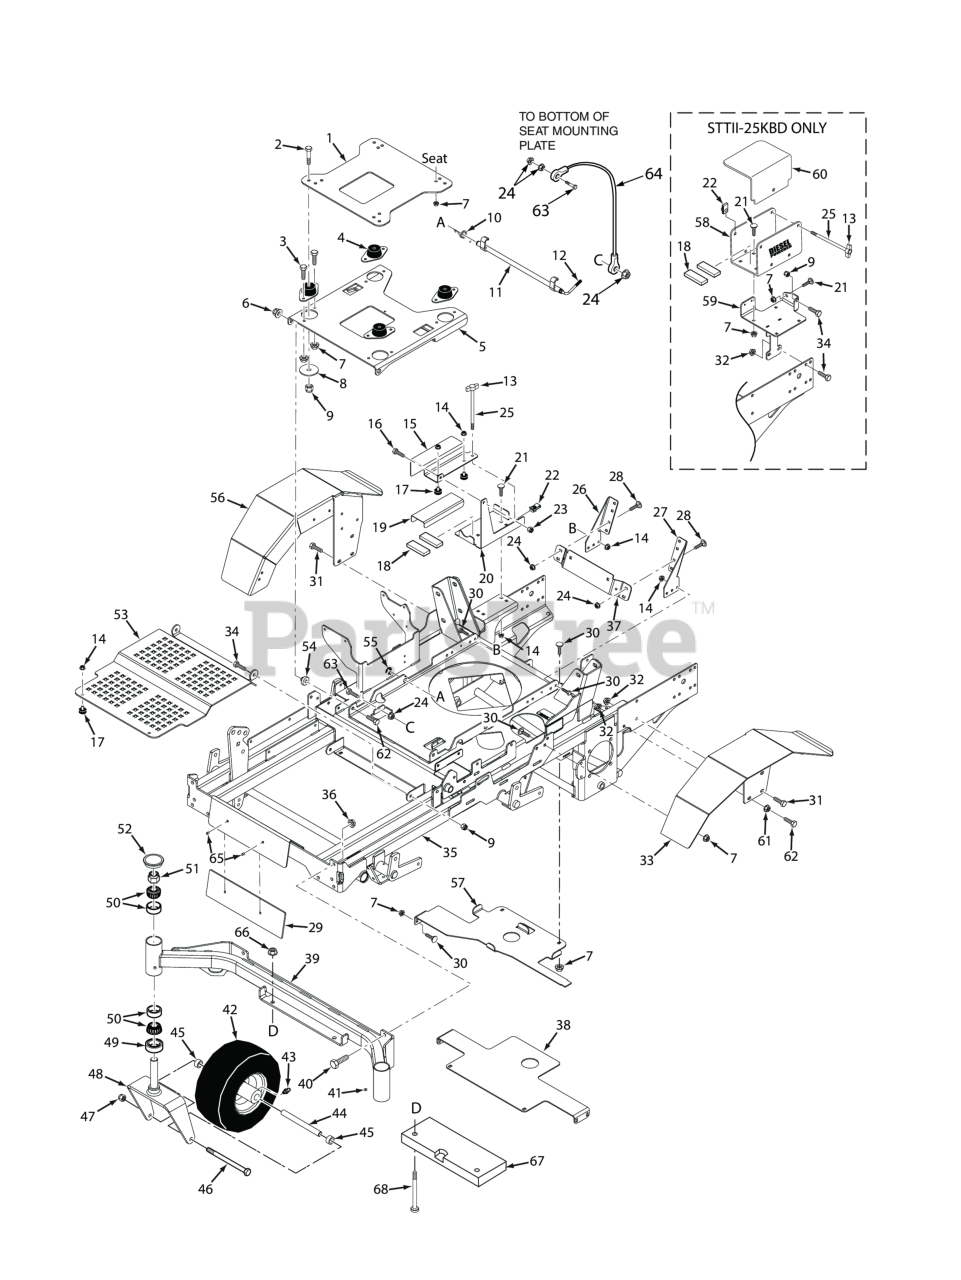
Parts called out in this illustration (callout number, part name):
1	Mounting Plate, Seat w/Decal
2	Bolt, Hex Head 3/8-16 x 2-1/4" - 61"
3	BOLT, SERRATED FLANGE HEX HEAD 5/16-18 X 3/4"
4	Isolator, Seat
5	Seat Mounting Plate, Lower w/Decals
6	Nut, Flange Elastic Stop Nut, 3/8-16
7	Nut, Serrated Flange 5/16-18 (Right Front Engine Mounting, Briggs and Kohler Only)
8	Flatwasher, 3/8-.406 x 2.25" x .1875
9	HEX NUT, ELASTIC STOP LOCK, 3/8-16
10	Spring, Seat Latch
11	Lever Assy., Seat Release
12	Grip, Seat Latch
13	Knob, 1/4" Wing
14	Nut, Serrated Flange 5/16-18 (Right Front Engine Mounting, Briggs and Kohler Only)
15	Cover, Battery Box w/ Decal (Gas & LP)
16	BOLT, SERRATED FLANGE HEX HEAD 5/16-18 X 3/4"
17	Bumper, Rubber 5/16-18 x 5/8"
18	PAD, BATTERY SUPPORT
19	Insulation, Battery Cover (Gas Only)
20	Battery Box (Gas Only)
21	Bolt, 5/16-18 x .75 RHSN Carriage
22	Bolt, Hex Head 3/8-16 x 1"
23	HEX NUT, ELASTIC STOP LOCK, 5/16-18
24	NUT, 1/4-20 SERRATED FLANGE HEX HEAD
25	Bolt, Hex Head 1/4-20 x 8"
26	Mounting Bracket, Cooler - RH
27	Mounting Bracket, Cooler - LH
28	Serr. Fl. Hex Head CPSCR, 1/4-20 x 3/4"
29	Backing Plate
30	Bolt, 5/16-18 x .75 RHSN Carriage
31	Capscrew, 3/8-16 x 1.0" Serrated Flange Hex Hd
32	Threaded Insert, 3/8-16
33	FENDER WLMT, LH
34	Bolt, Hex Head, 3/8-16 x 1 Gr. 5
35	Mainframe Assy., w/Decals
36	Nut, 7/16-14 Flange Elastic Stop
37	Bracket, Carbon Canister
38	Front Support, Fuel Tank
39	Caster Support Weldment - 52V
40	BOLT, HEX HEAD, 7/16-14 X 1-1/4
41	Plug, 1/4-28 THD Form
42	Wheel Assy, 61V, 72V (Incl. 20, 54, 55)
43	Grease Fitting
44	Sleeve, Caster Wheel (61V, 72A/VS)
45	Spacer, Caster Wheel
46	Bolt, Hex Head 1/2-13 x 9-1/2" (61V & 72A/VS)
47	HEX LOCKNUT, ELASTIC STOP, 1/2-13
48	Yoke Weldment
49	Seal, 2.00" O.D. x 1.625" Bore
50	Bearing Set
51	Nut, Elastic Stop 1.0"-14
52	Cap, Grease
53	Foot Plate
54	Sleeve, Seat Base Mounting
55	RETAINING RING, 5/8" EXTERNAL "E"
56	Fender, RH
57	Rear Support, Fuel Tank
58	Battery Box w/Decal (Diesel Only)
59	Battery Bracket Weldment (Diesel Only)
60	Cover, Battery (Diesel Only)
61	NUT, 3/8-16 SERRATED FLANGE HEX HEAD
62	Bolt, Hex Head 3/8-16 x 1-1/2" B&S 32BV
63	SERR. FLG. HEX HEAD CAPSCREW, 5/16-18 X 3/4
64	CABLE, SEAT STOP
65	Rivot, 3/16 x .402 POP
66	Nut, Hex Serrated Flange 1/2-13
67	Weight (61" cutter deck only)
68	CAPSCREW, 1/2-13 X 4.00 FHHS
